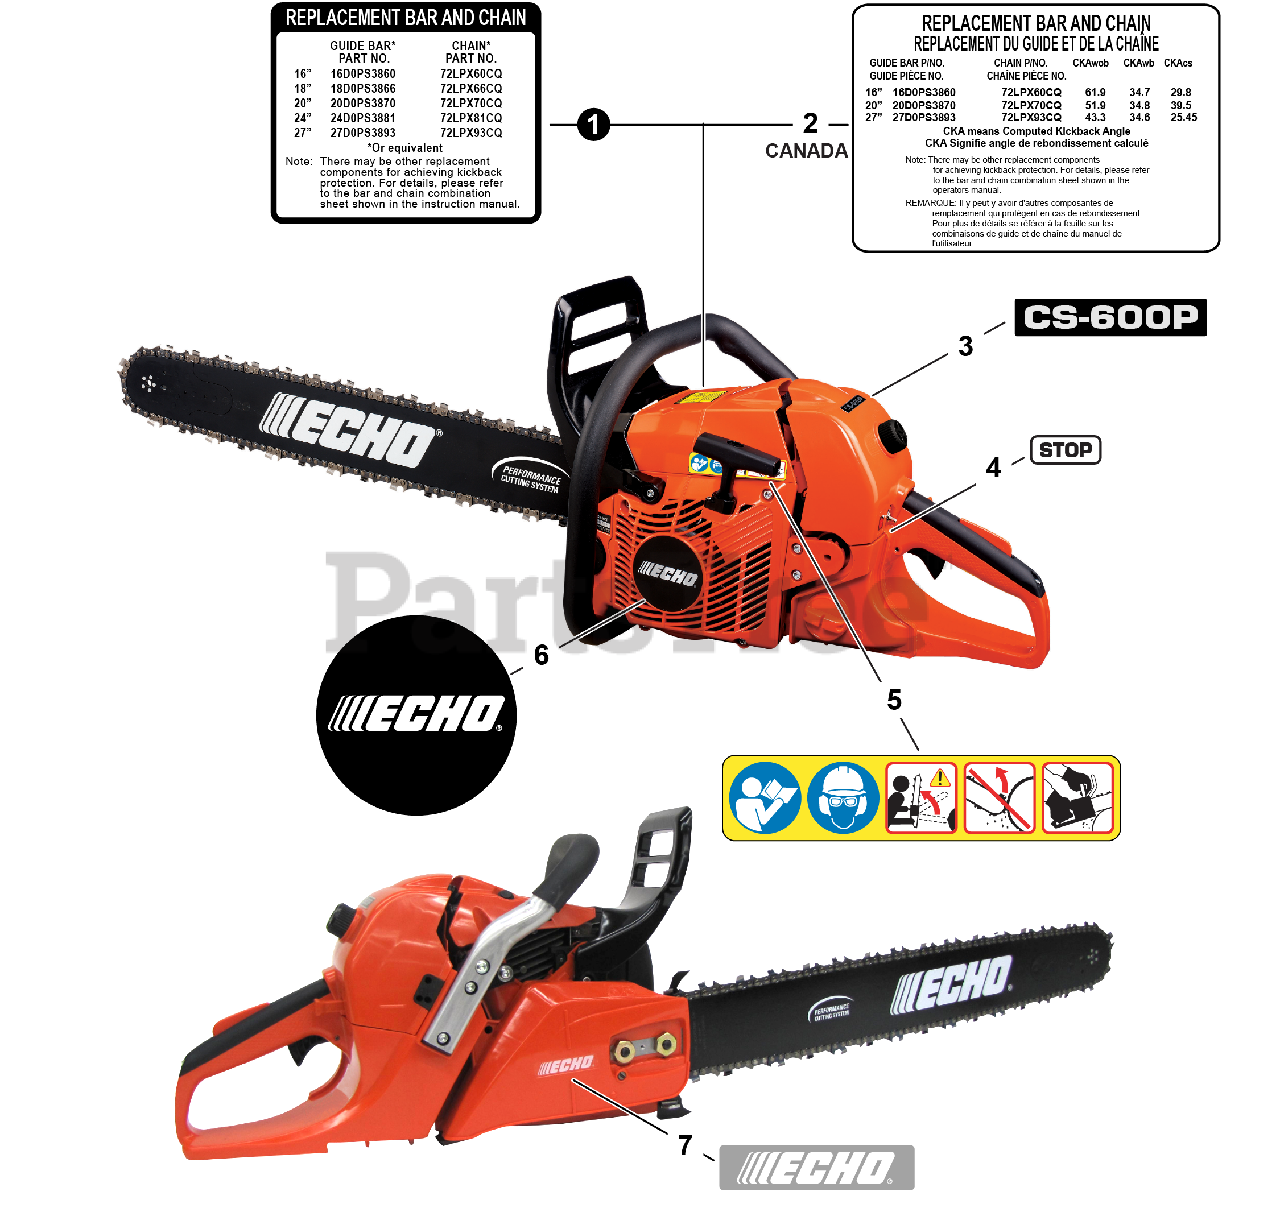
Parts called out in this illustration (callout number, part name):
1	LABEL, BAR & CHAIN
2	LABEL, BAR & CHAIN
3	LABEL, MODEL - CS-600P
4	LABEL, STOP
5	LABEL, CAUTION
6	LABEL, ECHO
7	LABEL, ECHO
